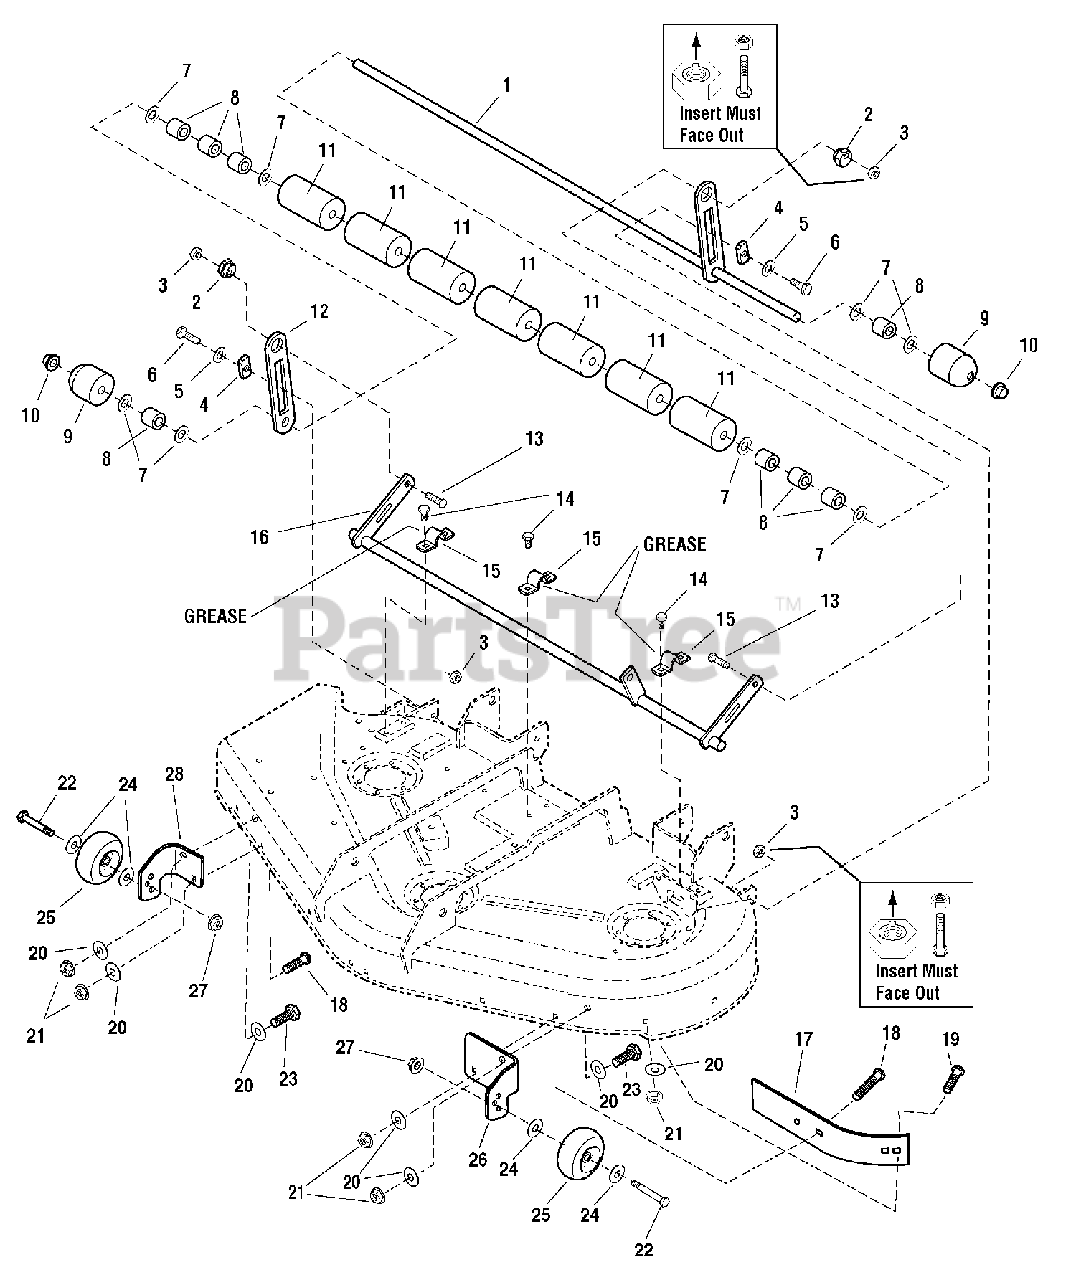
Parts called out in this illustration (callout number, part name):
1	SHAFT, Roller, 44"
2	NUT, Hex Adjusting, .99 DIA .687
3	NUT, Hex Aluminum Insert Lock, 3/8-16
5	WASHER, Plain, 1/2
6	BOLT, Shoulder, 3/8-16 X 1.34
7	WASHER, 5/8
8	SPACER, .66 ID
9	ROLLER, Rounded
10	NUT, Push
12	BAR, Roller
13	CARRIAGE BOLT, 3/8-16 X 1-1/2
14	CAPSCREW, Hex Head Taptite, 5/16-18 X 3/4
15	STRAP
16	SHAFT, Deck Lift, 44"
17	BAFFLE, Short Blowout
18	CARRIAGE BOLT, 5/16-18 X 1
19	CARRIAGE BOLT, 5/16-18 X 3/4
20	WASHER, 5/16, Plain, SAE
21	NUT, 5/16-18, Hex, Nylon Lock
22	BOLT, Rear Wheel
23	CAPSCREW, Hex Head, 5/16-18 X 1
24	WASHER
25	WHEEL, Guage
26	BRACKET, Gauge Wheel, LH, Orange
26	BRACKET, Gauge Wheel, LH, Red
27	NUT, 3/8-16 HEX NYLON FLANGE
28	BRACKET, Gauge Wheel, RH, Orange
28	BRACKET, Gauge Wheel, RH, Red
